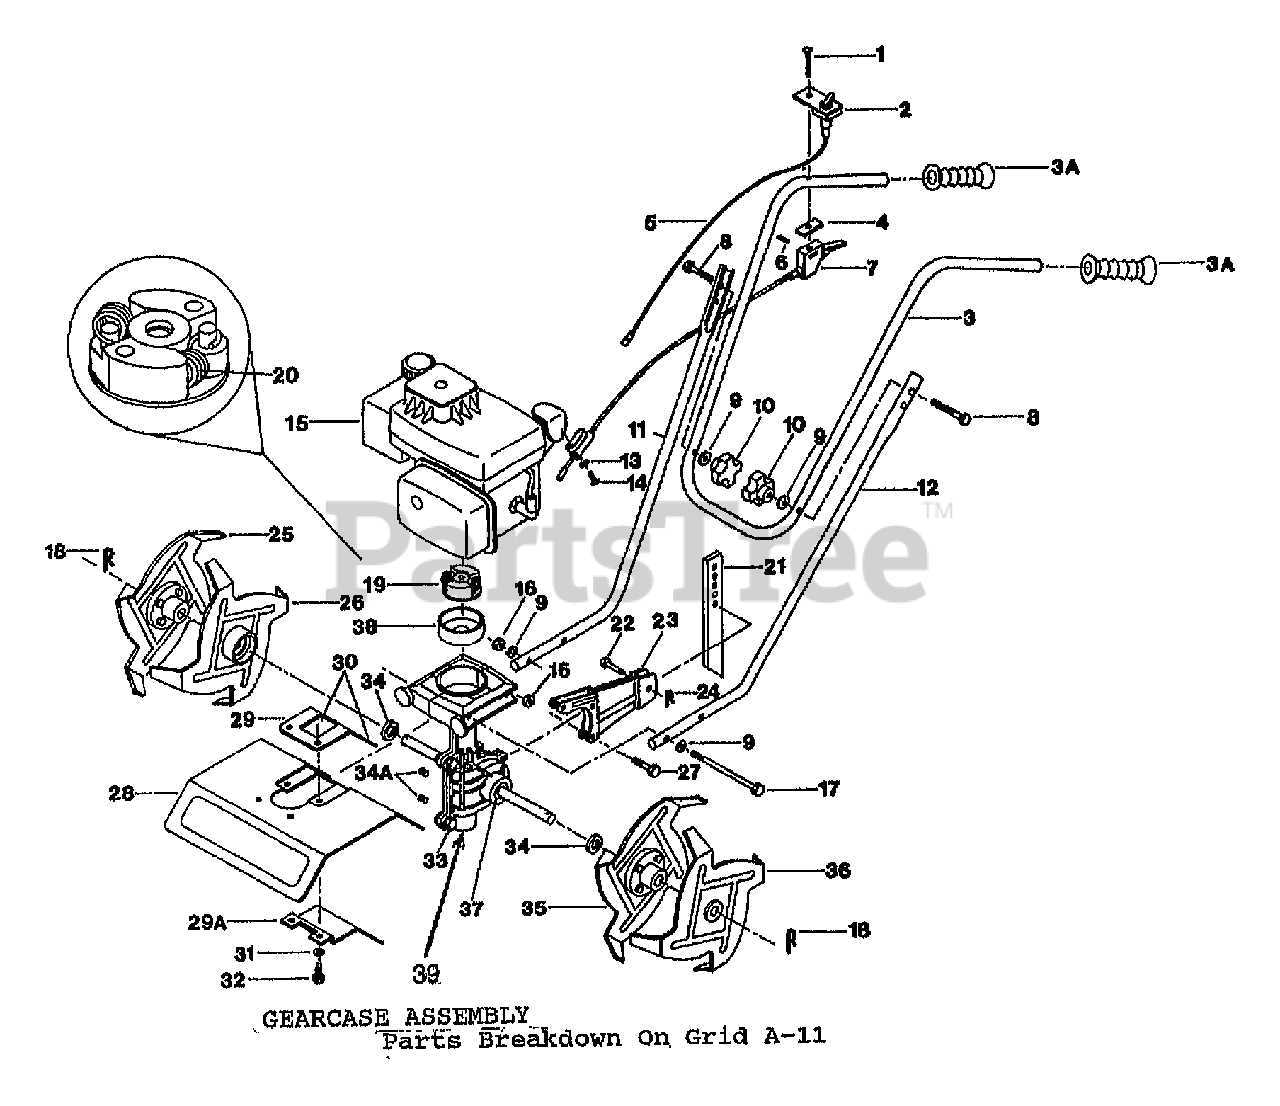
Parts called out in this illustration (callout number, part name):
1	SCR-PH HD M10-24X1.375
2	SWITCH-IGN. 96506
3	ASSM-UPR HANDLEBAR
3A	GRIP-HANDLEBAR 97030
4	PAD-ISOLATOR TRIGGER
5	HARNESS-WIRE
6	NUT-WELD #10-24
7	ASSM-TRIGGER & CABLE
8	SCR-CURVED HD 5/16-18X2.0
9	WASHER-BOW 1.0X.328X.059
11	H/BAR-LWR RIGHT PNT
12	H/BAR-LWR LEFT PNT
13	WASHER-FLAT SH
14	SCR-HH M8-32X1.0
15	ENGINE, TECUMSEH TC-200-2026C
16	LOCKNUT, 1/4-20
17	BOLT, HEX HEAD, 14-20 X 41/2
18	HAIRPIN COTTER
19	CLUTCH ROTOR
20	SPRING, CLUTCH
21	DRAG STAKE
22	PIN-CLEVIS, 5/16 X 7/8
23	DRAG STAKE BRACKET
24	HAIRPIN COTTER
25	TINE, OUTER RIGHT HAND SIDE
26	TINE, INNER RIGHT HAND SIDE
27	BOLT, 1/4-20 X 1 1/8" (ATTACHES DRAG STAKE TO TRANSMISSION)
28	TINE COVER W/DECALS
29	PLATE, REAR, TNE COVER
29A	ROCK SHIELD
30	SCREW, #10-32 X 1/2", SELF TAPPING, (FOR REAR TINE COVER PLATE)
31	LOCKWASHER, 1/4"
32	BOLT, 1/4-20 X 2"
33	BOLT, 1/4-20 X 7/8
34	DUST COVER SETSCREW
34A	AIR VENT SCREW/FILL HOLE SCREW
35	TINE, INNER LEFT HAND SIDE
36	TINE, OUTER LEFT HAND SIDE
37	WASHER, FELT
38	CLUTCH DRUM & HUB
39	TRANSMISSION ASSEMBLY
